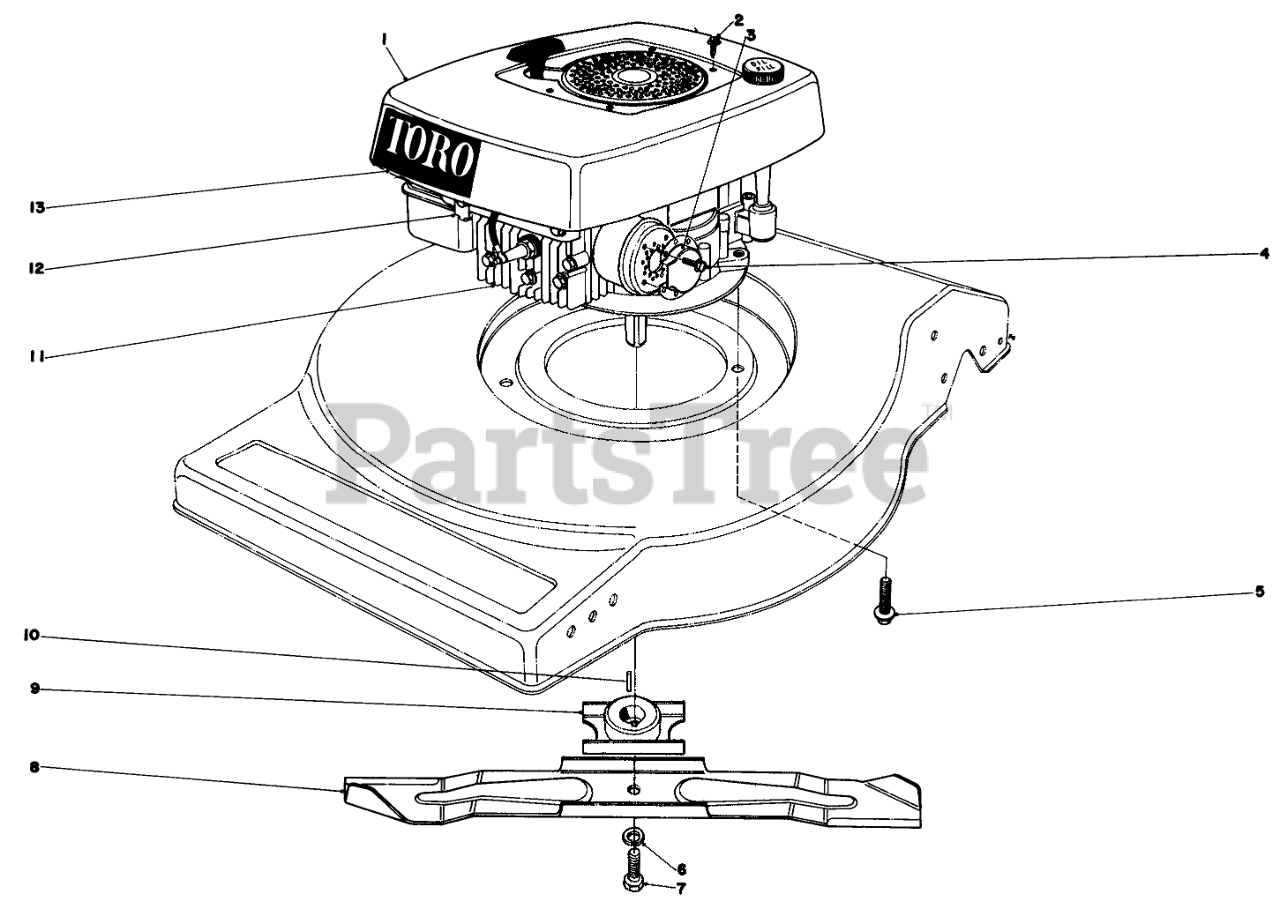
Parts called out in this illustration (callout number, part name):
1	SHROUD
2	8X1/2 SELF TAP SCREW
3	Deflector
4	SCREW W/ENGINE
5	SCREW-HWHTF
6	WASHER-LOCK
7	SPECIAL SCREW
8	Blade
9	Blade Retailer
10	KEY-SQUARE
11	Engine
12	Bracket Control
13	Decal Shroud
